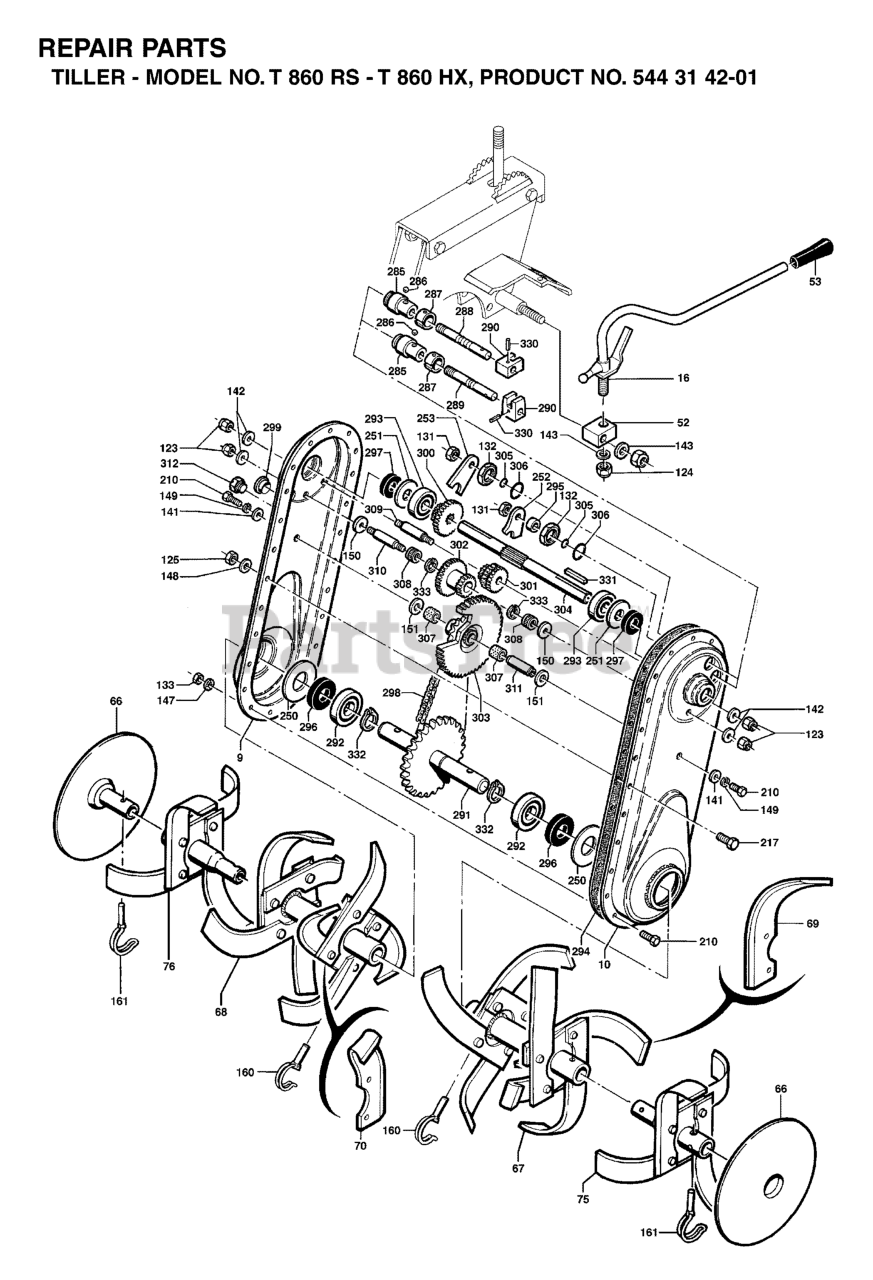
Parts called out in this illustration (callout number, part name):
121	Blocking nut M 6 Z
142	WASHER
167	COTTER PIN
